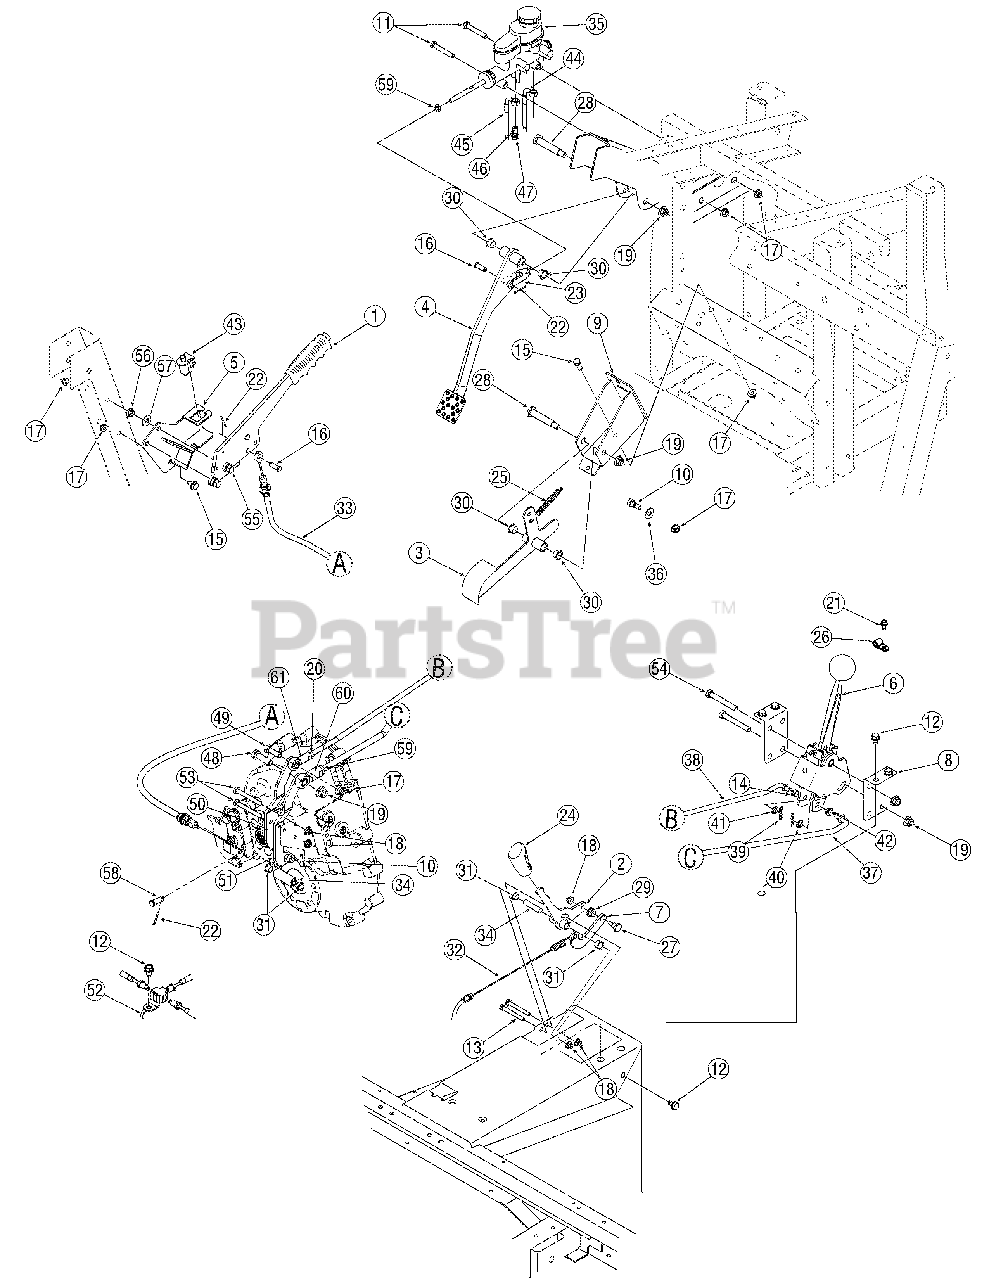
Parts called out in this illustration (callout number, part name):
1	Lvr Assembly, Brake
6	Shft Assembly, Hurst, 4x4
6	Shft Assembly, Hurst, 4x2
7	Plt, Pawl, Over Center
10	Scr, Shldr, .372 X .375, 5/16-18
11	Screw, 5/16-18, 2.00, Gr5, Patch
12	Scr, Tt, 5/16-18, 0.500
13	Screw, 1/4-20, 2.25, Gr5, Std
14	Brg., Flange, .315 ID
15	Screw, 5/16-18, .75, Gr5, Std
16	Pin, Clevis, 312 Od X 1.0"
17	Nut, Flglk, 5/16-18
18	Nut, Flglk, 1/4-20, Grf, Nylon
19	Nut, Flglk, 3/8-16, Grf, Nylon
20	Nut, Jam, 5/16-24, Gr5
21	Screw, Tt, 1/4-20 x .500
22	Pin, Cot, 3/32, 1.0
23	Yoke, 5/16-24
24	Hndl, Selct
25	Spr, Extn, .38 Od X 3.6
26	Clamp, Hose
27	Scr, Shldr, .375x.380, 1/4-20
28	Scr, Shldr, .500 X 2.230, 3/8-16
29	Plastic Bushing .380 Id
30	Brg, Flg, Nyliner, .500idx.34lg
31	Brg, Flg, .375 X .580 X .250
32	Cbl, Cont, Diff, Lock
33	Cbl, Cont, Park, Brake, 4x4
34	Spcr, Pivot, Diff Lock
35	Cyl, Master, Tandem, Hayes
36	Wash, Flat, .349 X .879 X .063
37	Link, Shft, F N R
38	Link, Shft, Hi Lo, 4x4
39	Pin, Cotter, 1/16 x .75
39	Pin, Cotter, .072 Dia. x 1.13 Lg.
40	Wash, Flat, .385 X .62 X .063
41	Wash, Flat, .330 X .630 X .0635
42	Brg, Flg, .377 Id
43	Switch
44	Hose, Brake, Master Cyl, Front
45	Hose, Brake, Master Cyl, Rear
46	Ftg, Banjo Ftg Bolt, M10 x 1.00
47	Ftg, Banjo Ftg Crush Wash
48	Screw, 3/8-16 x 1.25
49	Screw, 5/16-18 x 1.25
50	Lvr., Assembly, Shift, Hi-Lo, 4x4
51	Lvr., Assembly, Shift, F N R
52	Ftg., Tee, -3, 45 Deg Flare
53	Screw, 1/4-20 x 2.50
54	Screw, 3/8-16 x 2.75
55	Screw, 5/16-18 x 2.00
56	Nut, Jam, 5/16-18
57	Washer, Flat, .344 x .688 x .065
58	Pin, Clevis
59	Nut, Jam, 3/8-24
60	Rod, End, 3/8 ID
61	Rod, End, 5/16 ID
